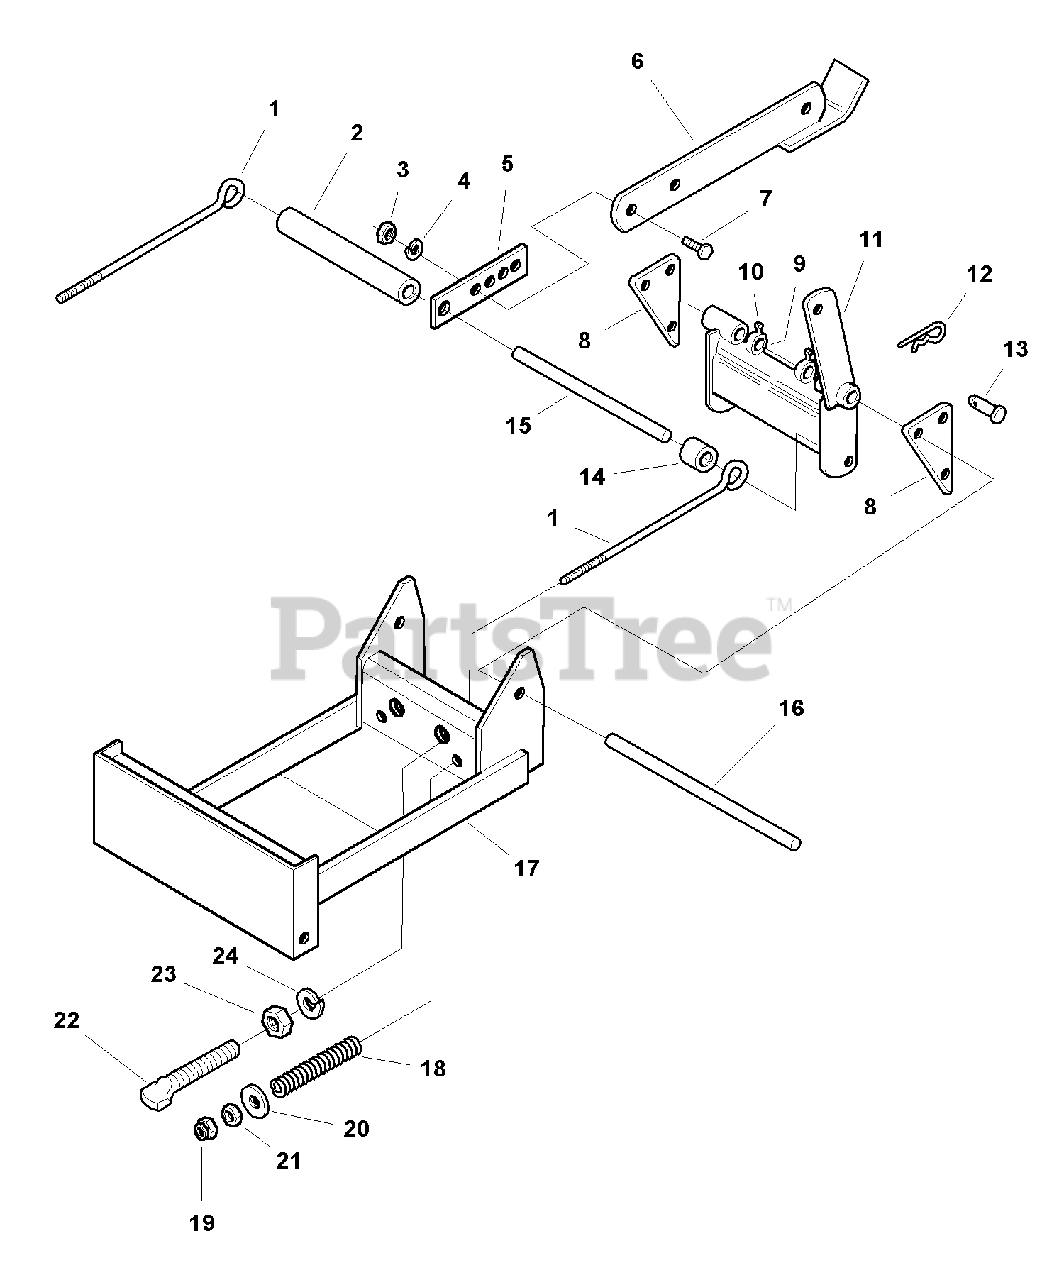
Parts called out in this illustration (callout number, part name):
1	EYEBOLT, 3/8-16
3	NUT, Hex, 1/2-13
4	LOCKWASHER, 1/2
5	BAR, Lift, Front
6	LIFT BAR ASSEMBLY
7	CAPSCREW, Hex Head, 1/2-13 x 1-3/4
8	ANCHOR, Front
9	SET COLLAR
10	SETSCREW, Square Head, Cup Point, 5/16-18 x 1/2, G8
11	PIVOT ASSEMBLY, Hitch
12	CLIP, Safety
13	PIN, Clevis, 5/8 x 2-1/4
16	SHAFT, Inner
17	HITCH ASSEMBLY
18	SPRING, Compression
19	NUT, Hex Jam, 3/8-16
20	WASHER, 3/8
21	NUT, Hex, 3/8-16
22	STUD, 3/4-10 UNC-2A
23	NUT, Hex, 3/4-10
24	LOCKWASHER, 3/4
